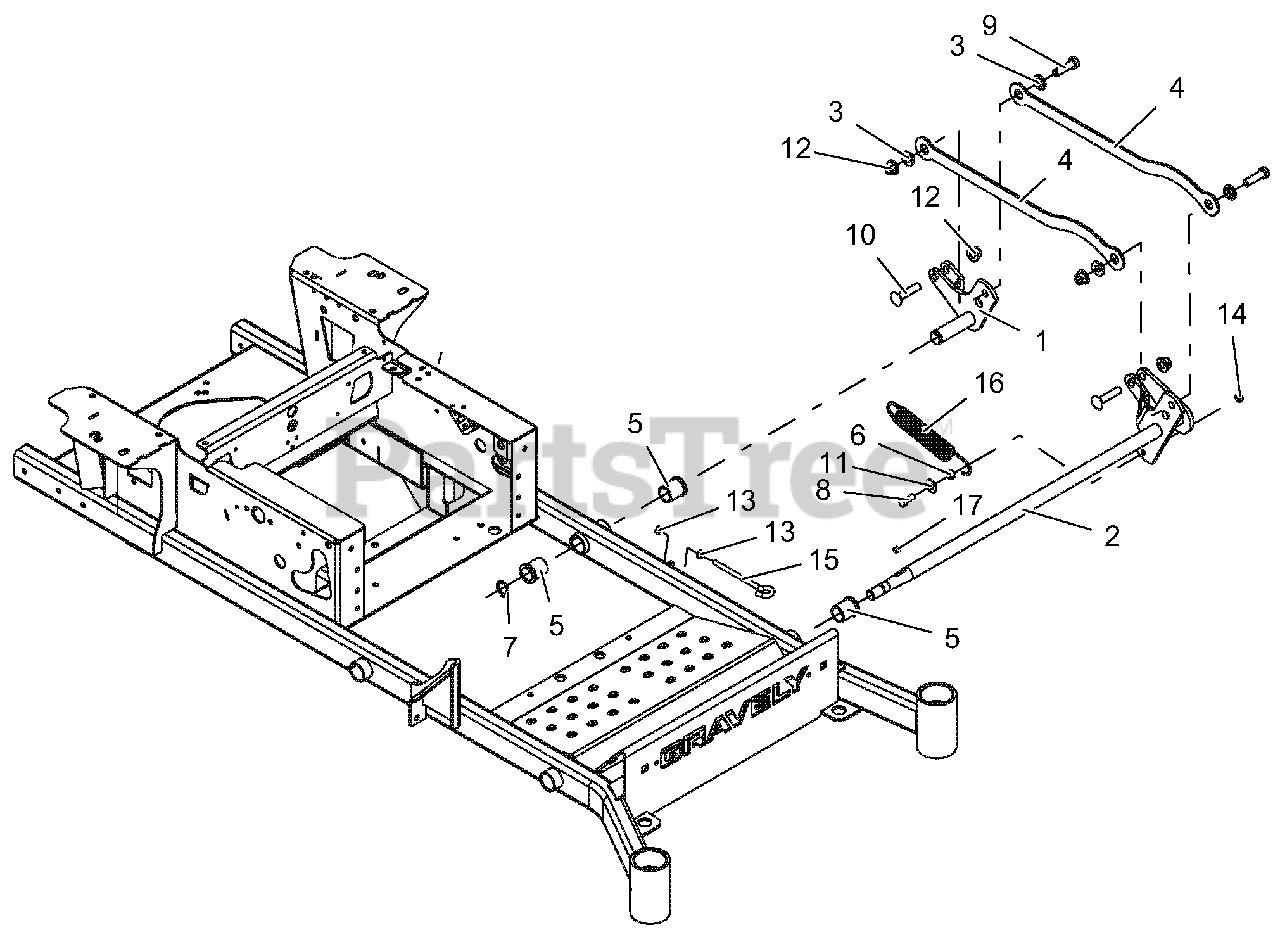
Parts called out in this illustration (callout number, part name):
1	WLDMT, LH REAR DECK LIFT
2	WLDMT, PT100 FRONT LH DECK LIFT-BLACK
3	BSHG, FLANGE .515X.750X.31X1.12
4	LINK, LIFT - BLK
5	BSHG-FLG 1.00X1.25X1.5X1.5
6	BSHG, SLV .377X.624X.235
7	RG-RTNG-EXT 1.00X.078
8	BLT-HEX .38-16X1.00 GR5 YWZC
9	BLT-HEX .50-13X1.75 GR5 YWZC
10	BLT-RDHDSQNK .50-13X2.25 G5 Y
11	WSHR-FL-STL.438X1.00X.083 YWZC
12	NUT-LK-NYL-FLG .50-13 YWZC
13	NUT, JAM .375-16 YWZC
14	@NUT-LK-CTR-JAM .375-16 YWZC
15	BOLT, EYE .38-16X6.00 .62 DIA
16	SPRG, EXTENSION
17	KEY, WDRF .25 X 1.00 HRD #15
